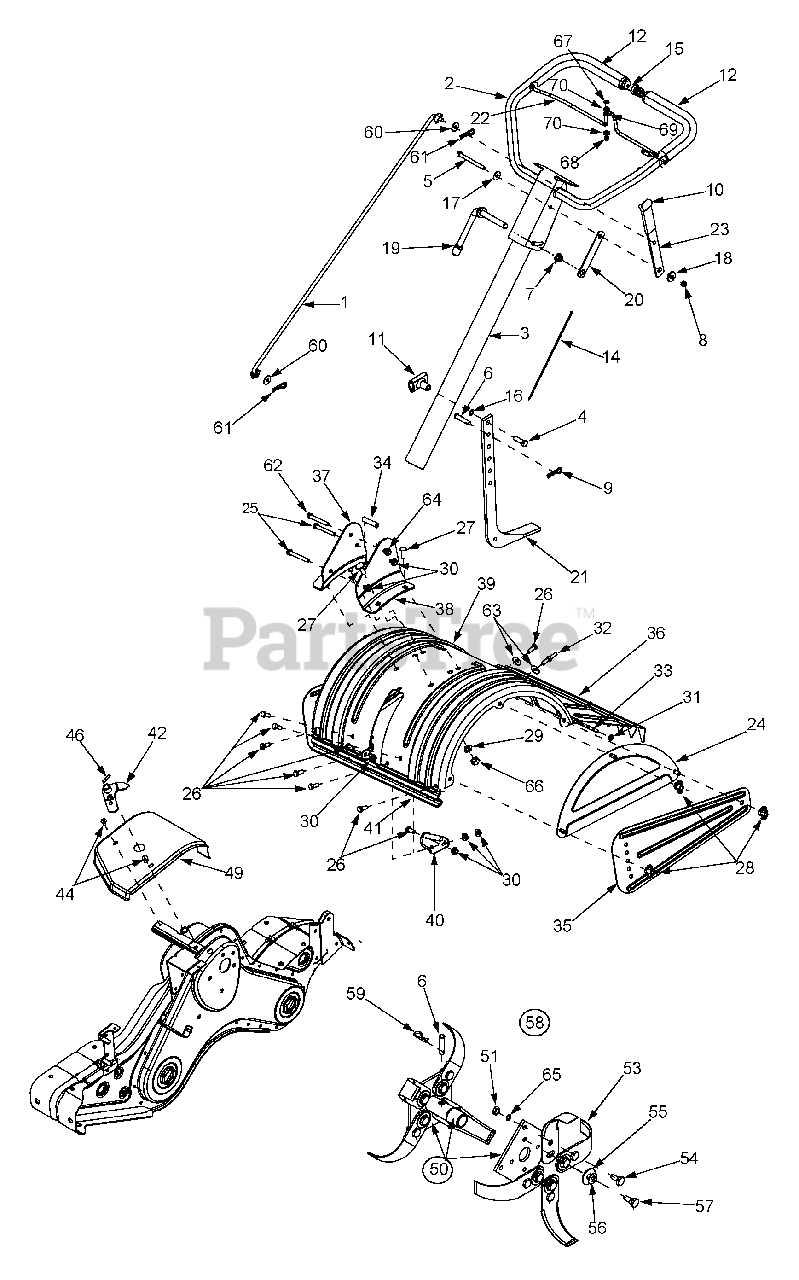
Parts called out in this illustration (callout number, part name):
1	Shift Rod
4	Hex Screw 3/8-16 x 1.25
5	Hex Screw 5/16-18 x 3.25
6	Clevis Pin 3/8-1.62
7	Flange Lock Nut 3/8-24
8	Hex Lock Nut 5/16-18
9	Cotter Pin
11	T-Knob
12	Foam Grip
14	Cable Tie
15	End Plug
16	Flat Washer 3/8 ID x.620 OD
17	Bell Washer.340 ID x.872 OD
18	Shoulder Spacer
19	Handle Adjustment Crank
20	Hex Nut Retainer Bracket
25	Hex Cap Screw 5/16-18 x 2.75
26	Hex Cap Screw 5/16-18 x.750
27	Carriage Bolt 3/8-16 x 1.0
28	Wing Nut
29	Lock Washer 3/8
30	Flange Nut 5/16-18
31	Cap Nut
32	Hex Screw 5/16-18 x.75"
34	Spacer.322 x.625 x 2.0
42	Shift Crank Ass'y
44	Screw 1/4-14 x.625
46	Spiral Pin 3/16 x 1.0
51	Hex Nut 3/8-24
54	Shoulder Bolt
55	Flat Washer.51" ID x 1.50" OD
56	Bell Washer.515" ID x 1.14" OD
57	Shoulder Bolt
59	Internal Cotter Pin
60	Rubber Washer
61	Cotter Pin
62	Hex Screw 3/8-16 x 2.75"
63	Flat Washer
64	Flange Nut.344 ID x.62 OD
65	Lock Washer
66	Hex Nut 3/8-16
67	Truss Screw 1/4-20 x.65
68	Hex Lock Nut 1/4-20
69	Battery Hose Clamp 5/16
70	Flat Washer.260 ID x.720 OD
